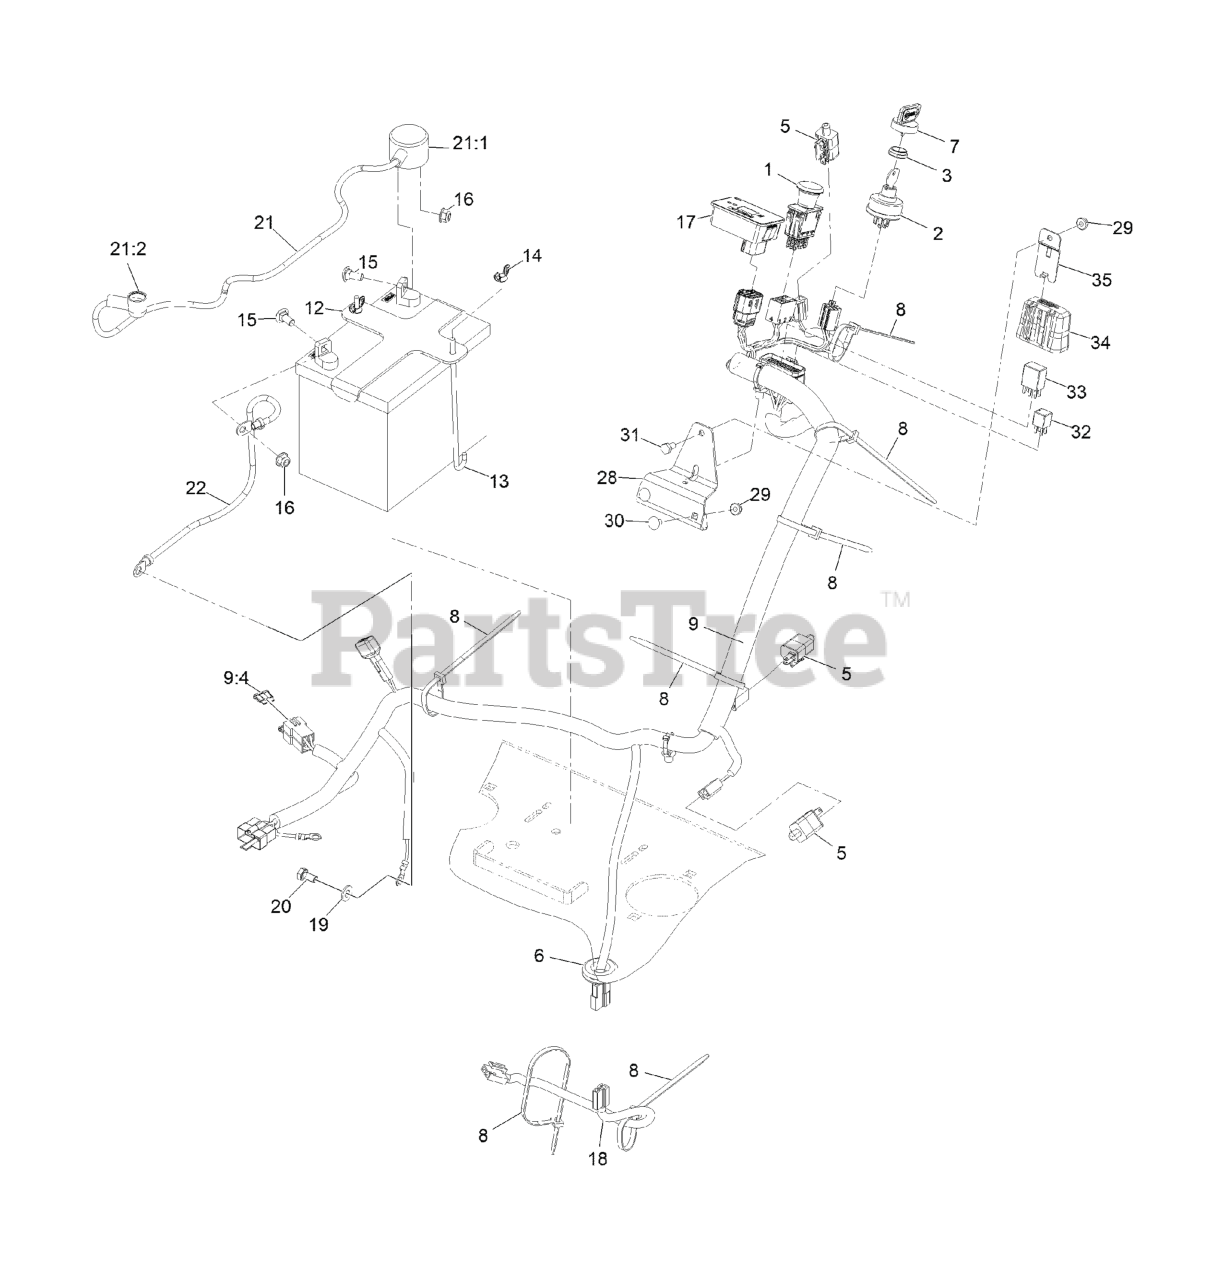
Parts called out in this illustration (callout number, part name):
1	SWITCH-PTO
2	SWITCH, KEY START
3	NUT-SWITCH, IGNITION
6	GROMMET
7	KEY-IGNITION
8	TIE-CABLE
9	HARNESS-WIRING
9:4	FUSE-BLADE TYPE, 20 AMP
12	BRACKET, BATTERY HOLD DOWN
13	BOLT-HOLDDOWN
14	WINGNUT
15	BOLT-CARR
16	NUT-HF, NI
17	MODULE-HOUR METER
18	HARNESS-CLUTCH PIGTAIL
19	WASHER-PLAIN
20	SCREW-HH
21	POSITIVE BATTERY CABLE AS
21:1	INSULATOR-SOLENOID
21:2	INSULATOR-BATTERY
28	BRACKET, MOUNTING PDM
30	SCREW-CARR
31	SCREW-HH
32	RELAY-MICRO
33	RELAY-MICRO 280, SPDT
34	COVER-BLOCK, FUSE
35	CLIP-MOUNTING
